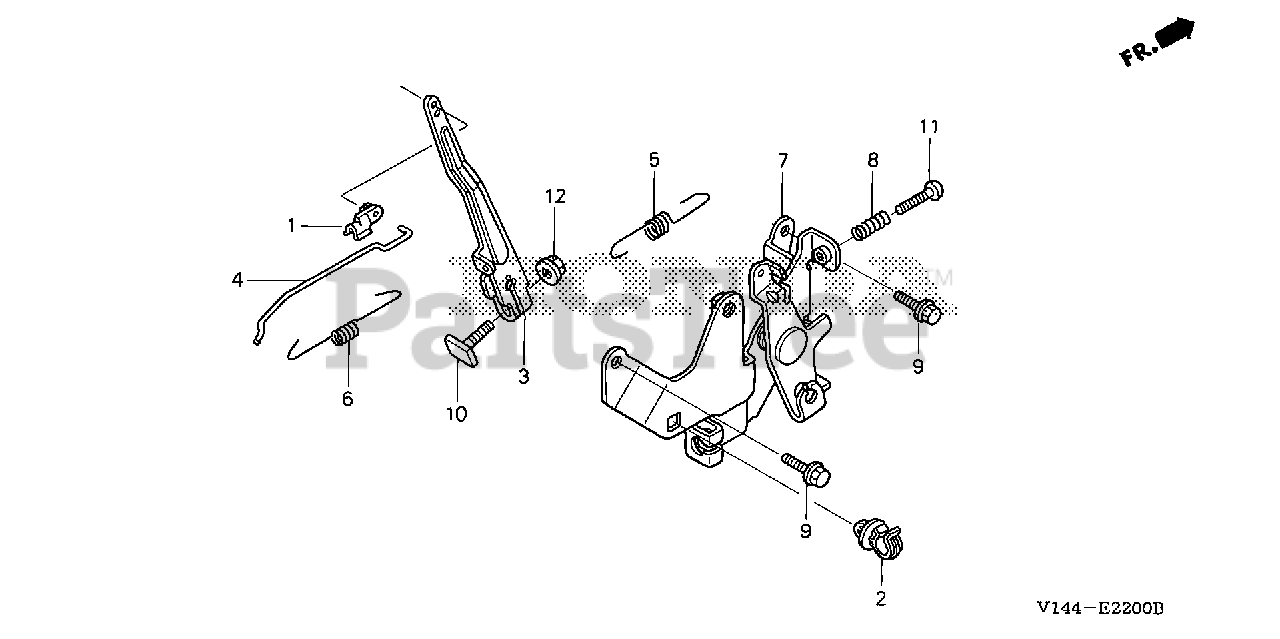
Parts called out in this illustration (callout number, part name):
1	JOINT, ROD
2	CLAMP, FUEL TUBE
3	ARM, GOVERNOR
4	ROD, GOVERNOR
5	SPRING, GOVERNOR
6	SPRING, THROTTLE RETURN
7	BASE, CONTROL
8	SPRING, CONTROL ADJUSTING Use from Engine SN 2327377.
9	BOLT, FLANGE (5X12)
10	BOLT, GOVERNOR ARM
11	SCREW, PAN (5X20)
12	NUT, FLANGE (6MM)
